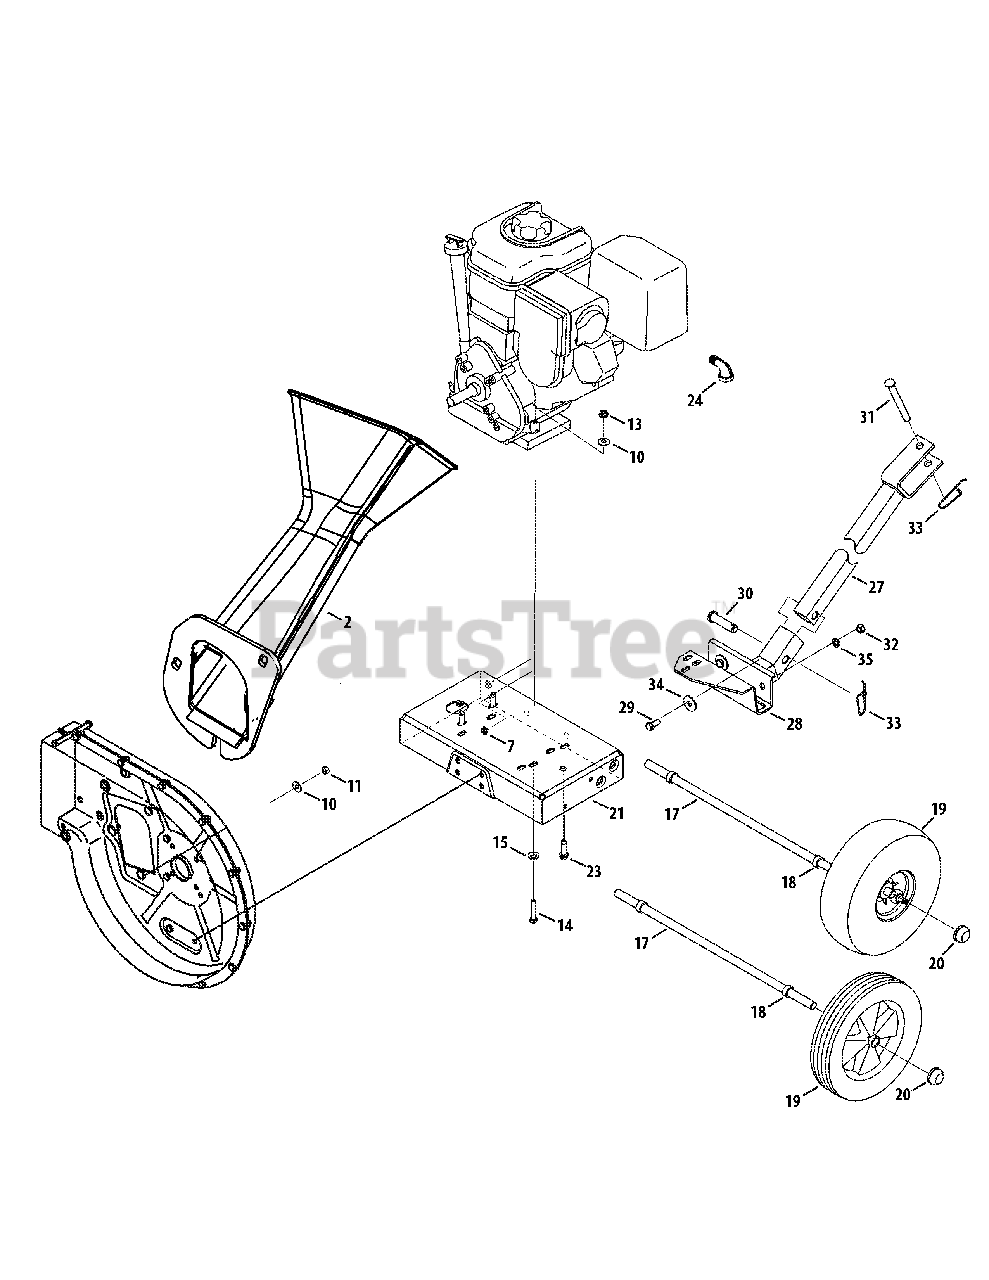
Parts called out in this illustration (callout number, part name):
2	Chipper Shredder Chute
10	Bell Washer.340 ID x.872 OD
11	Hex Nut 5/16-18
13	Hex Lock Nut 5/16-18
14	Hex Cap Screw 5/16-18 x 1.50
15	Bell Washer 5/16 x 1.0
17	Axle Assembly
18	Spacer
19	Wheel Comp., 10.0 x 2.5 Plastic
20	Push Cap
21	Frame
23	Screw, 3/8-16 x 1.250
24	Elbow Fitting
27	Tongue Hitch Mount
28	Base Hitch Mount
29	Hex Cap Screw, 3/8-16 x.88
30	Clevis Pin,.625 x 2.4
31	Clevis Pin,.50 x 4.62
32	Flange Lock Nut, 3/8-16
33	Spring Pin
34	Flat Washer,.411 x 1.25 x 1.0
35	Lock Washer, 3/8
